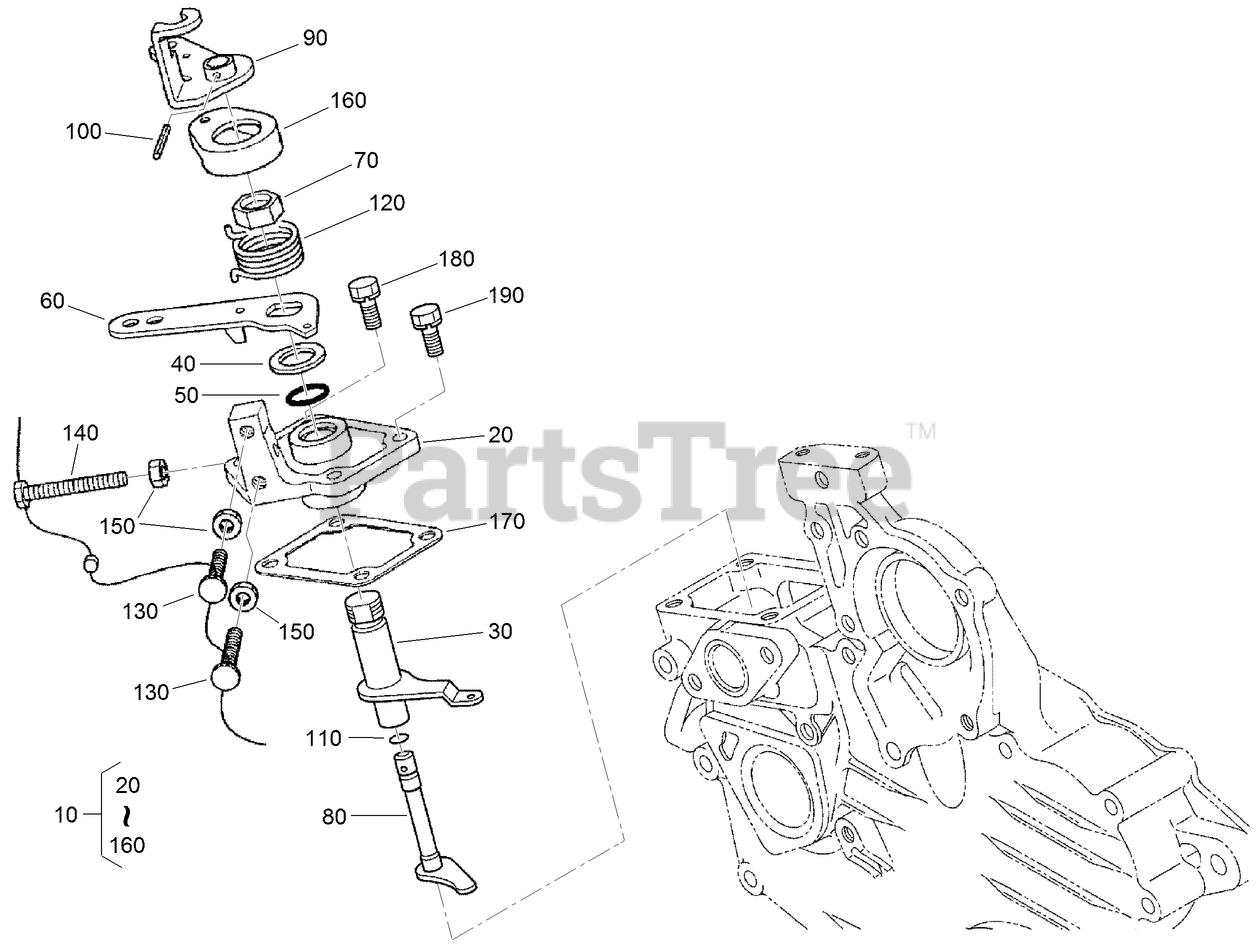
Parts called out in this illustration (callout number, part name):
10	SPEED CONTROL PLATE ASM
20	PLATE-CONTROL, SPEED
30	LEVER-GOVERNOR
40	COLLAR
50	O-RING
60	LEVER-CONTROL, SPEED
70	NUT-CONTROL, SPEED
80	SHAFT-LEVER
90	LEVER-STOP, ENGINE
100	PIN-SPRING
110	O-RING
120	SPRING-RETURN
130	SCREW-STOPPER
170	GASKET-PLATE, CONTROL
180	BOLT-FLANGE
